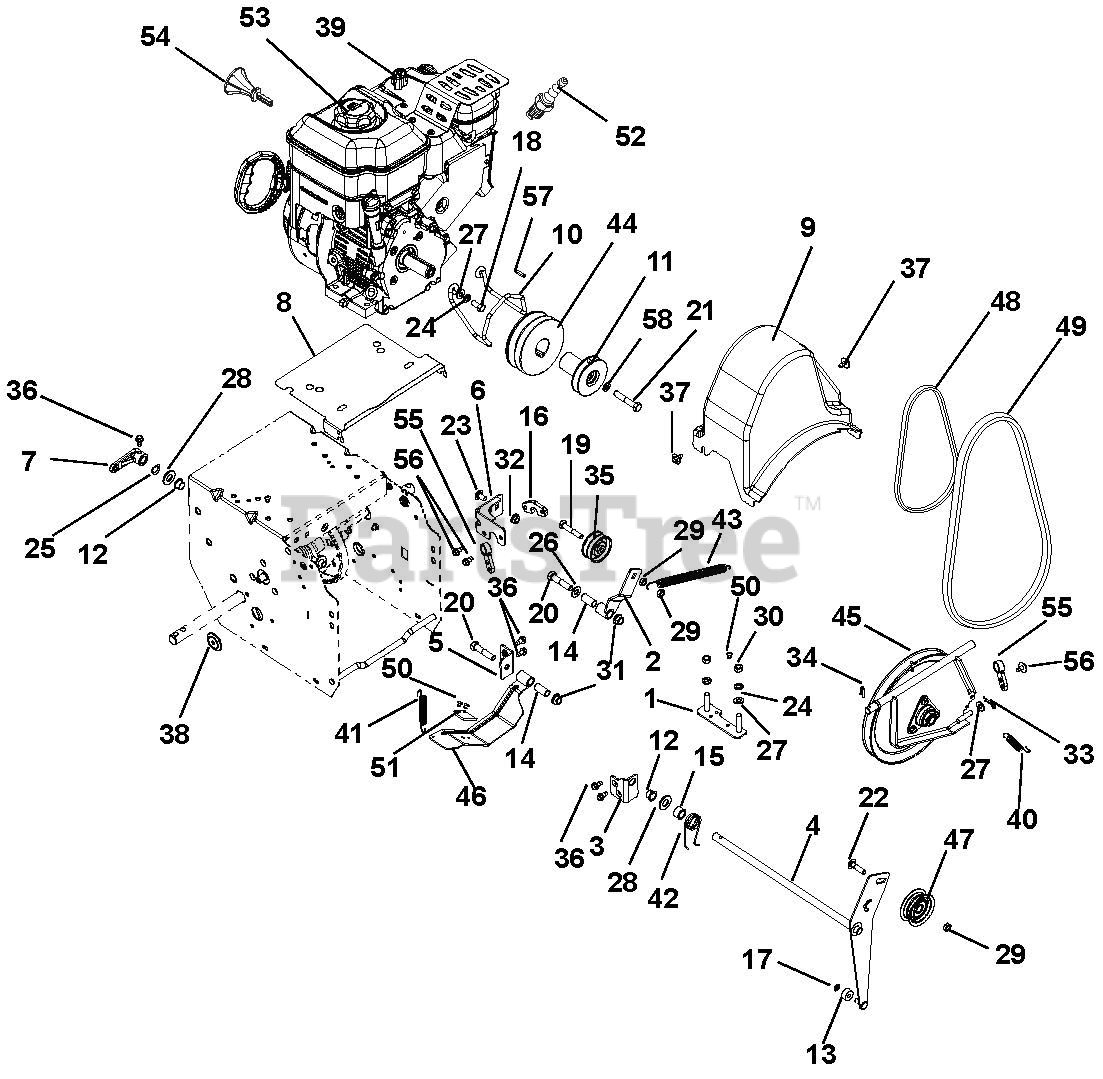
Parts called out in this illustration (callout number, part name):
1	STRAP, ENGINE BOLT-WELDMENT
2	ARM, TRACTION IDLER
3	BRACKET, MOUNT - IDLER ARM
4	WELDMENT, ATTACHMENT IDLER ARM
5	BRACKET, MOUNT - BRAKE
6	WELDMENT, FRAME BRACKET
7	ARM, CLUTCH - ATTACHMENT
8	BAFFLE,ENGINE,SMALL BLOCK
9	COVER, COMPACT BELT
10	FINGER, BELT
11	SHEAVE,AUGER 3/4" PM
12	BUSHING, POLYLINER-.50 SPLIT
13	BSHG,SLV .265 X .625 X .375
14	BSHG-SLV .385X.500X1.045
15	BSHG-SLV .510X.751X.475
16	SPACER, SWING GATE
17	RG-RTNG-EXT .250X.010
18	BLT-HEX .31-24X.75 YWZC GR5
19	@BLT-HEX .31-18X1.75 GR5 YWZC
20	@BLT-HEX .38-16X1.75 GR5 YWZC
21	@BLT-HEX .31-24X1.75 GR5 YWZC
21	BLT-HEX .38-24X2.0 YWZC
22	BLT-RDHDSQSHNK.31-18X1.13 G5YZ
23	@BLT-RHDSSQNK .31-18X.62 G5YZ
24	WSHR-LK .312X.097 HVY YWZC
25	WSHR-WAVE .50X.75X.015 .13FRHT
26	@WSHR-FL-STL.406X.812X.065 YWZ
27	@WSHR-FL-STL.344X.688X.065YWZC
28	@WSHR-FL-STL.531X1.06X.095YWZC
29	@NUT-LK-CTR-JAM .31-18 YWZC
30	@NUT-HEX .31-18 YWZC
31	@NUT-LK-TOP-FLG .38-16 YWZC
32	@NUT-LK-TOP-FLG .31-18 YWZC
33	PIN-HAIR INT .08X.18X1.18 YWZC
34	CLIP, SPRING
35	KIT, FLAT IDLER
36	SCR-TAP .25-20X.50 HWH TR YWZ
37	SCR-TAP .25-20X.5 CAPTIVE
38	PLUG, HOLE - 1.00" FLEXTEMP
39	ENGINE, ARIENS 208CC 120V, 60W
39	ENGINE, ARIENS AX208 120V/60W
39	ENGINE, ARIENS AX208 240V/60W
39	ENGINE, B&S 208CC, 240V
39	ENGINE, BRIGGS 208, 120V 60W
39	ENGINE, BRIGGS 900, RECOIL 60W
40	SPRING, EXT. .043X.438X1.64
41	SPRING-EXT .437 X .438 X 2.64
42	SG-TORS .075 X .955
43	SPRING, EXTENSION
43	SPRING, SWIVEL HOOK EXTENSION
44	SHEAVE, TRACTION
44	SHEAVE, TRACTION-COMPACT TRACK
45	PLATE, SWING - ASSEMBLY
46	BRAKE ARM W/PAD
47	KIT, FLAT IDLER
48	V-BELT, 3L-WRAPPED
49	V-BELT, HA-RAW EDGE
50	RVT-POP .187 YZ
51	PAD, BRAKE
52	PLUG, SPARK
53	CAP, FUEL TANK BLACK
53	CAP, FUEL - BRIGGS & STRATTON
54	KEY, PUSH/PULL LCT (2/PACKAGE)
54	KEY, IGNITION ROTARY B&S
54	KEY, IGNITION PUSH/PULL B&S
55	SUPPORT BUSHING, SWING GATE
56	SCR-TAP-PM .25-20X.75 TR YWZ
57	KEY-SQ .188X.75X.188
58	WSHR-LK .312X.097 HVY YWZC
58	@WSHR-LK .38X.094 REG YWZC
